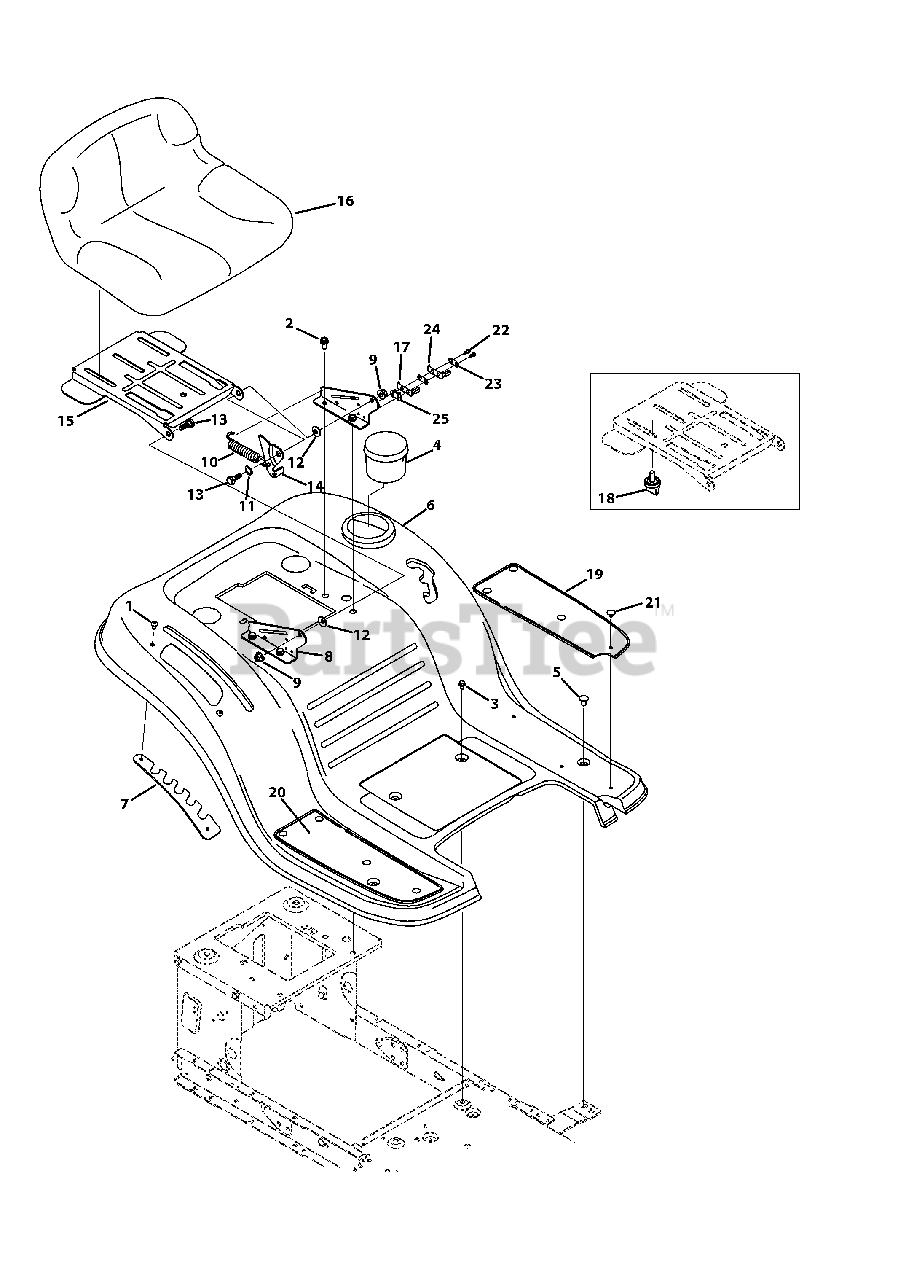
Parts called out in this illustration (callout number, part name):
1	Screw, 1/4-20 x .500
2	Screw, 5/16-18 x .750
3	Screw Pan Torx Head, 1/4-20 x .500
5	Screw Carriage, 1/4-20 x .62
6	Fender - Red
7	Lift Adjuster Bracket
8	Seat Mount Bracket
9	Flangelock Nut, 5/16-18
10	Extension Spring
11	Flat Washer, .510x .750 x .033
12	Bell Washer, .340 x .872 x .060
13	Shoulder Screw, 5/16-18 x .437 x .268
14	Lift Seat Bracket
15	Pivot Seat Manual Adjust Bracket
16	Med. Back Seat, Black
17	Inner Seat Spring
18	Knob, 3/8-16 x .875
19	Foot Pad, LH
20	Foot Pad, RH
21	Ratchet Clip, .250 x .500
22	Screw, 8-18 x .500
23	Insulator Plate
24	Outer Seat SPring
25	Insulator Boss Plate
